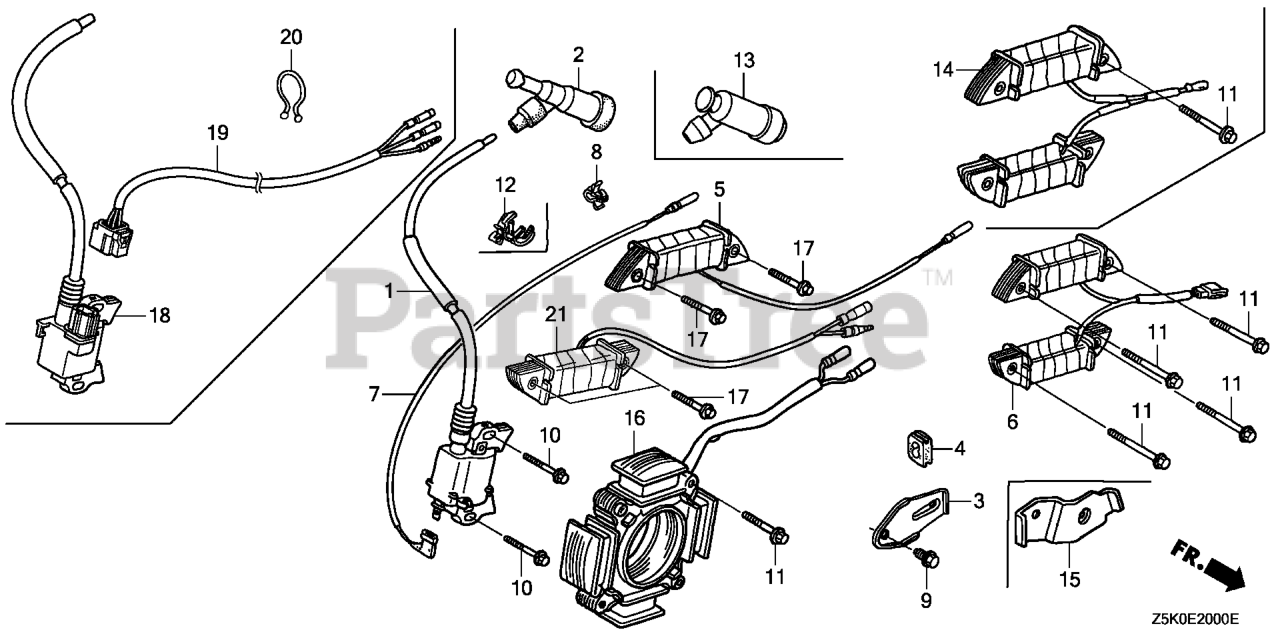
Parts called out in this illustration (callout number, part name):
2	CAP ASSY., NOISE SUPPRESSOR (NGK Y-EZD)
3	CLAMP, WIRE
4	GROMMET, WIRE
9	BOLT, FLANGE (6X12) (CT200)
10	BOLT, FLANGE (6X28) (CT200) Use up to Engine SN 1530314.
12	CLIP, WIRE HARNESS
17	BOLT, FLANGE (6X28) (CT200) Use up to Engine SN 1530314.
18	COIL ASSY., IGNITION
19	WIRE HARNESS ASSY., ENGINE
21	COIL ASSY., LAMP (12V/25W)
